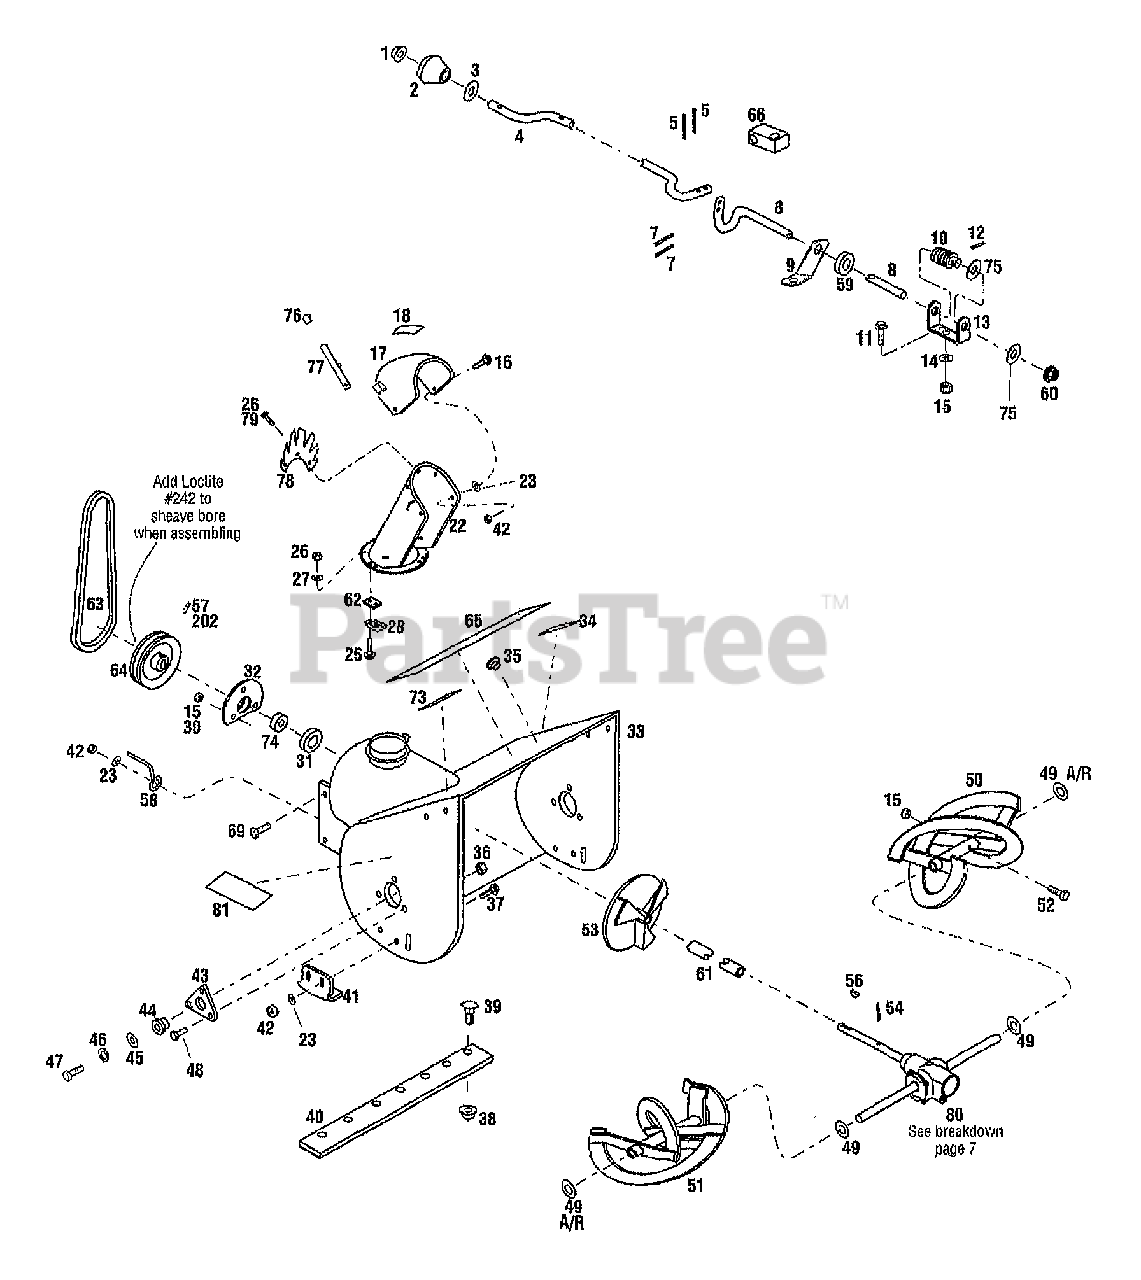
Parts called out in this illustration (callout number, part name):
1	NUT-PUSH 3/8 ZP
2	KNOB
3	WASHER-FLAT .375DIA
4	CRANK-CHUTE CONTROL
5	PIN-COTTER .093X.625
7	PIN-ROLL 1/8 X 3/4
8	SHAFT-CHUTE CONTROL
9	SUPPORT-CRANK
10	GEAR-WORM LH
11	SCR-HFLK 5/16-18X.75 ZP
12	PIN-DRIVE .09X.75
13	SUPPORT-GEAR
14	WASHER-FLAT 5/16 SAE
15	NUT-TOP/LK 5/16-18 ZP
16	SCR-HH 3/8-16X.75 G5 ZP
17	CAP-DISCH W/DECAL 5HP SNOW
18	DECAL-WARNING
22	ASSM-CHUTE
23	WASHER-FLAT 3/8 SAE
25	SCR-HW M10-24X.88 EXTTOOTH
26	NUT-HEX TOP LK 10-24 NYLK
27	WASHER-.505X.22X.05
28	CLIP-HOLD DOWN
30	SCR-HH 5/16-18X.63 G5
31	BEARING-BALL
32	RETAIN-BEARING
33	ASSM-HOUSING
34	DECAL-WARNING
36	NUT-HT LK 1/4-20
37	BOLT-3/8-16 X 3/4
38	NUT-HFLK 5/16-18 ZP
39	SCR-CARR 5/16-18X.50 G5 ZP
40	BLADE-SCRAPER
41	RUNNER-SKIP
42	NUT-LOCK 3/8-16
43	SUPPORT-BEARING
44	BUSHING-FLANGE
45	WASHER-1/2 FLAT
46	WASHER-LK .5
47	SCR-HH 1/2-13X.75 G5 ZP
48	SCR-HH 1/4-20X.625 G5 ZP
49	WASHER-SPEC
50	ASSM-AUGER BLADE LH
51	ASSM-AUGER BLADE RH
52	SCR-SHEAR 5/16-18X1.75
53	ASSM-IMPELLER
54	PIN-ROLL 1/4 X 1-1/4
56	KEY-HI PRO .187X.75
57	SCR-SET SQ 5/16-18X5/8
58	GUIDE-BELT
59	BUSHING-NYLON
60	NUT-HF/LK 3/8-16
61	SLEEVE
64	SHEAVE-CASTER
65	DECAL-LOGO
66	BLOCK-SWIVEL NYLON
69	SCR-HFLK 5/16-18X.75
73	DECAL-AMERICAN LEGEND-LRG
74	SHIM-1.75X1.26X.02
75	BUSHING-NYLON
76	GRIP-VACUCUT
77	LEVER-ADJUSTING
78	DEFLECTOR-CHUTE
79	SCR-TR HD 10-24X.375
80	ASSM-GEAR CASE
81	DECAL-HOUSING SIDE
202	LOCTITE-242 (.5 ML TUBE)
